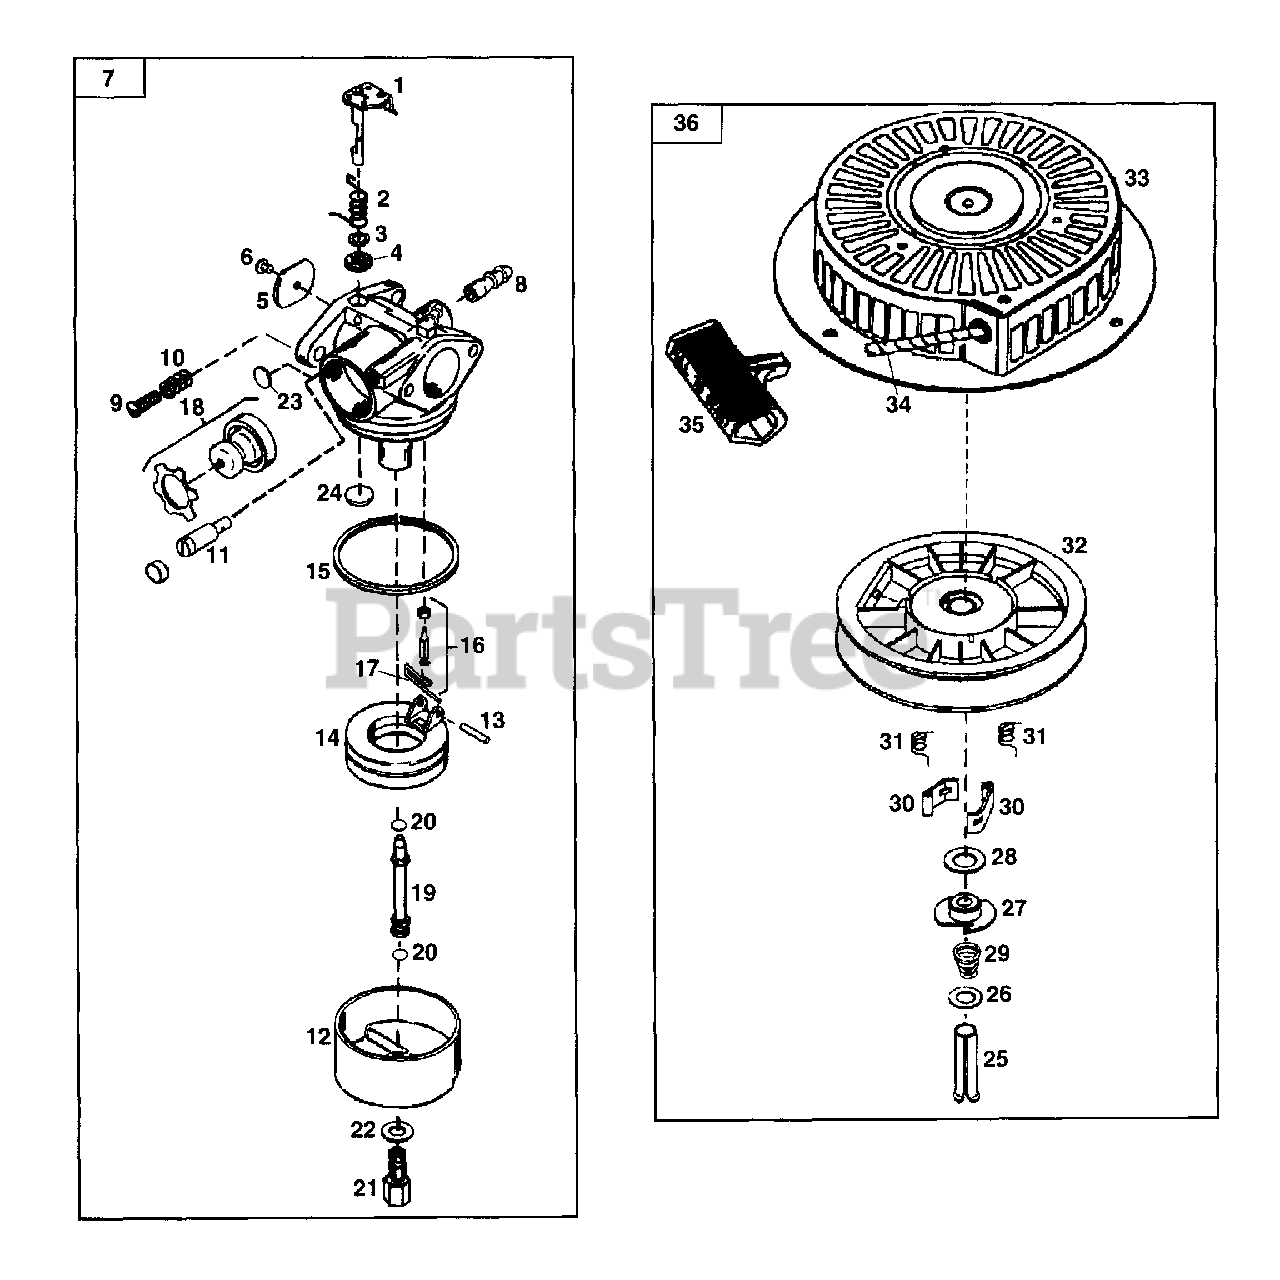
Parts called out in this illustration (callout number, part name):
1	Throttle Shaft & Lever Ass'y
2	Throttle Return Spring
3	Dust Seal Washer
4	Dust Seal (Throttle)
5	Throttle Shutter
6	Shutter Screw
7	Carburetor Assembly
8	Fuel Fitting
9	Throttle Crack/Idle-Speed Screw
10	Tension Spring
11	Idle Restrictor Screw
12	Float Bowl
13	Float Shaft
14	Float
15	Float Bowl "O" Ring
16	Inlet Needle, Seat & Clip
17	Spring Clip
18	Primer Bulb/Retainer Ring
19	Main Nozzle Tube
20	Main Nozzle Tube "O" Ring
21	High Speed Bowl Nut
22	Bowl Nut Washer
23	Welch Plug, Idle Mixture Well
24	Welch Plug, Atmospheric Vent
25	Spring Pin
29	Brake Spring
30	Starter Dog
31	Dog Spring
32	Pulley & Rewind Spring Ass'y
33	Starter Housing Ass'y
34	Starter Rope (98")
35	Starter Handle
36	Rewind Starter Ass'y
